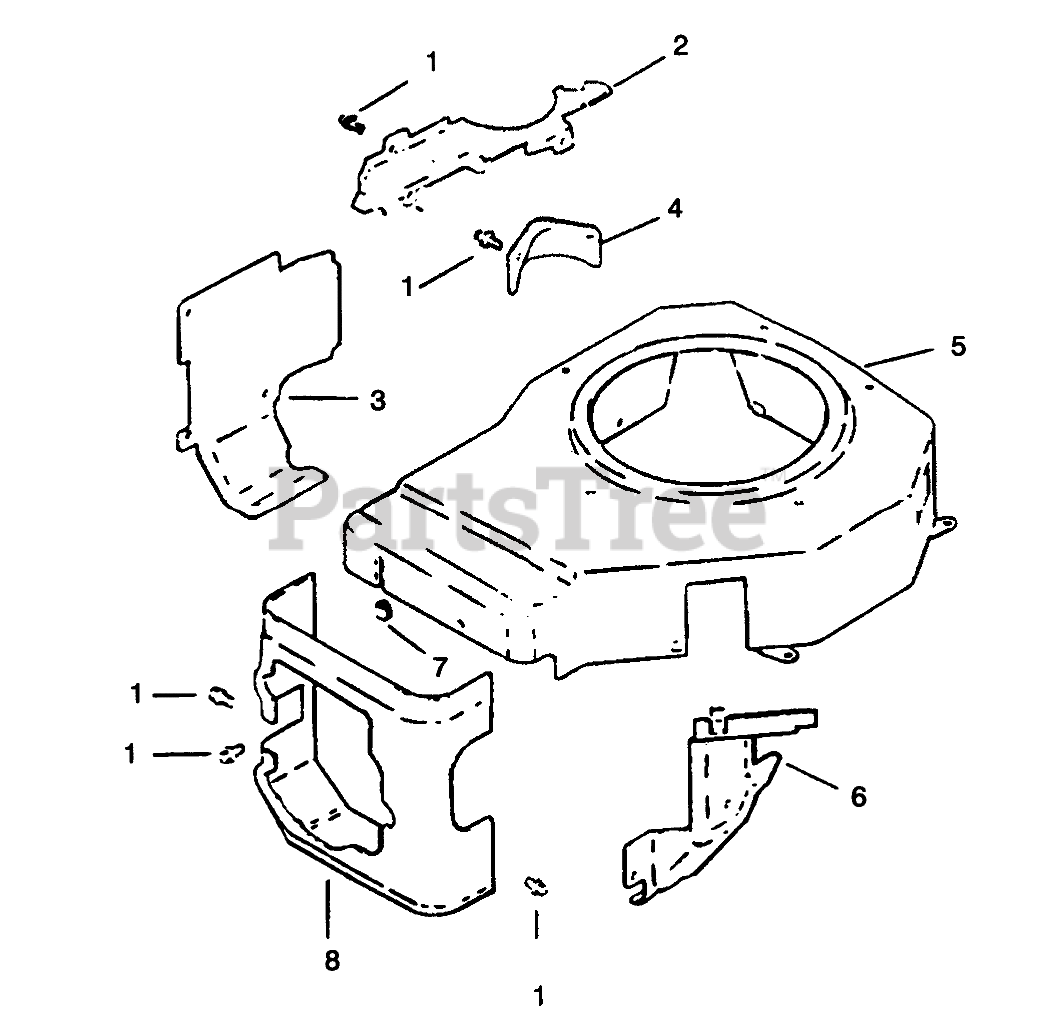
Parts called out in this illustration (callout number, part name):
1	Screw
2	Plate-Blower Housing
3	Baffle-Cylinder
4	Cover-Starter
5	Housing-Blower
6	Baffle-Carburetor
7	Grommet-Blower
8	Baffle-Cyl. Head
